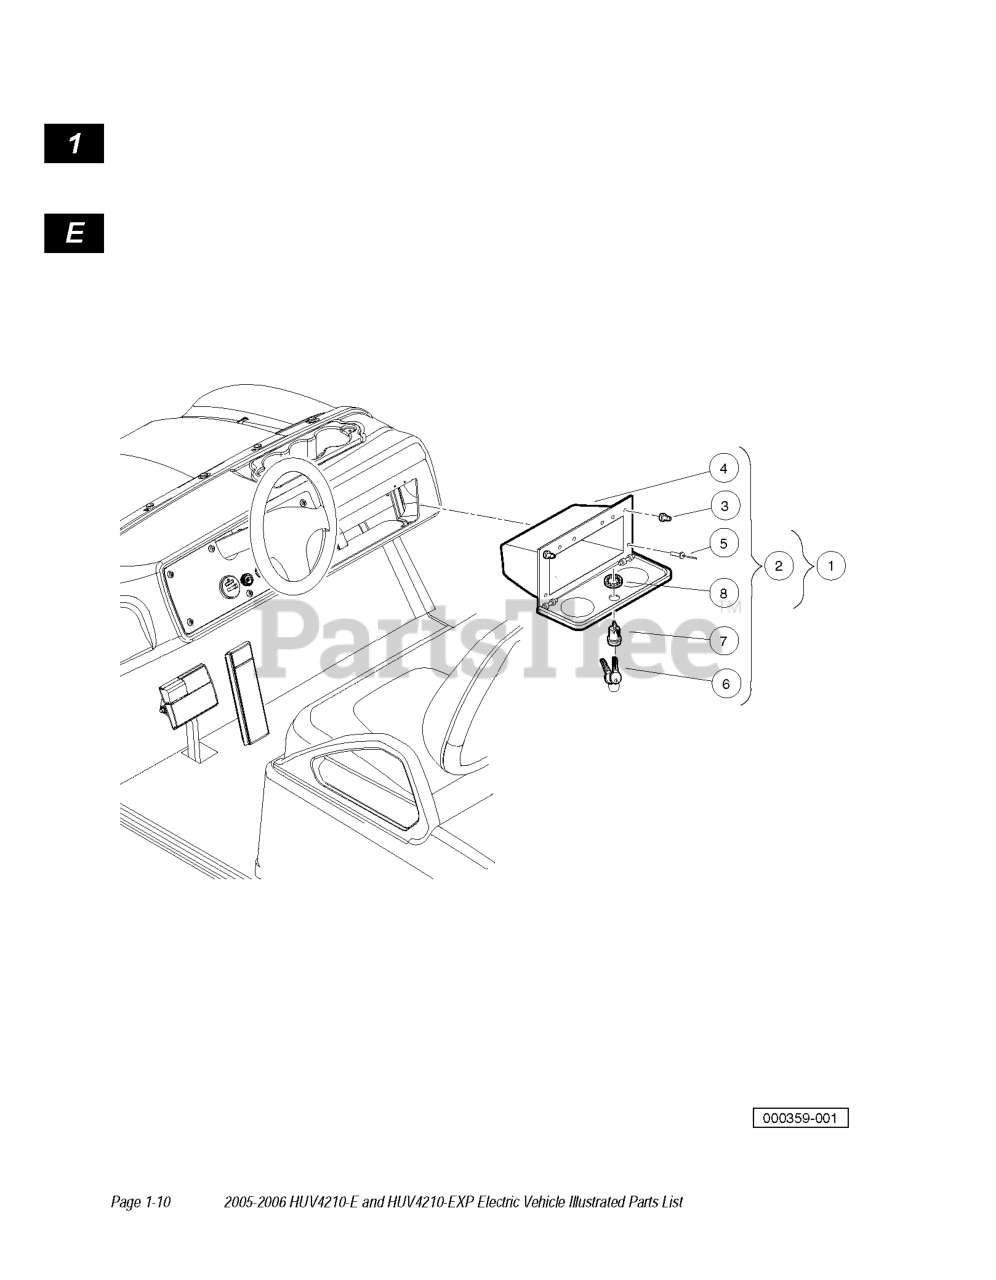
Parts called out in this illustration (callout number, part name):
1	GLOVE BOX LOCK / KEY KIT
2	Asm, Glove Box Lock / Key
3	RUBBER BUMPER
